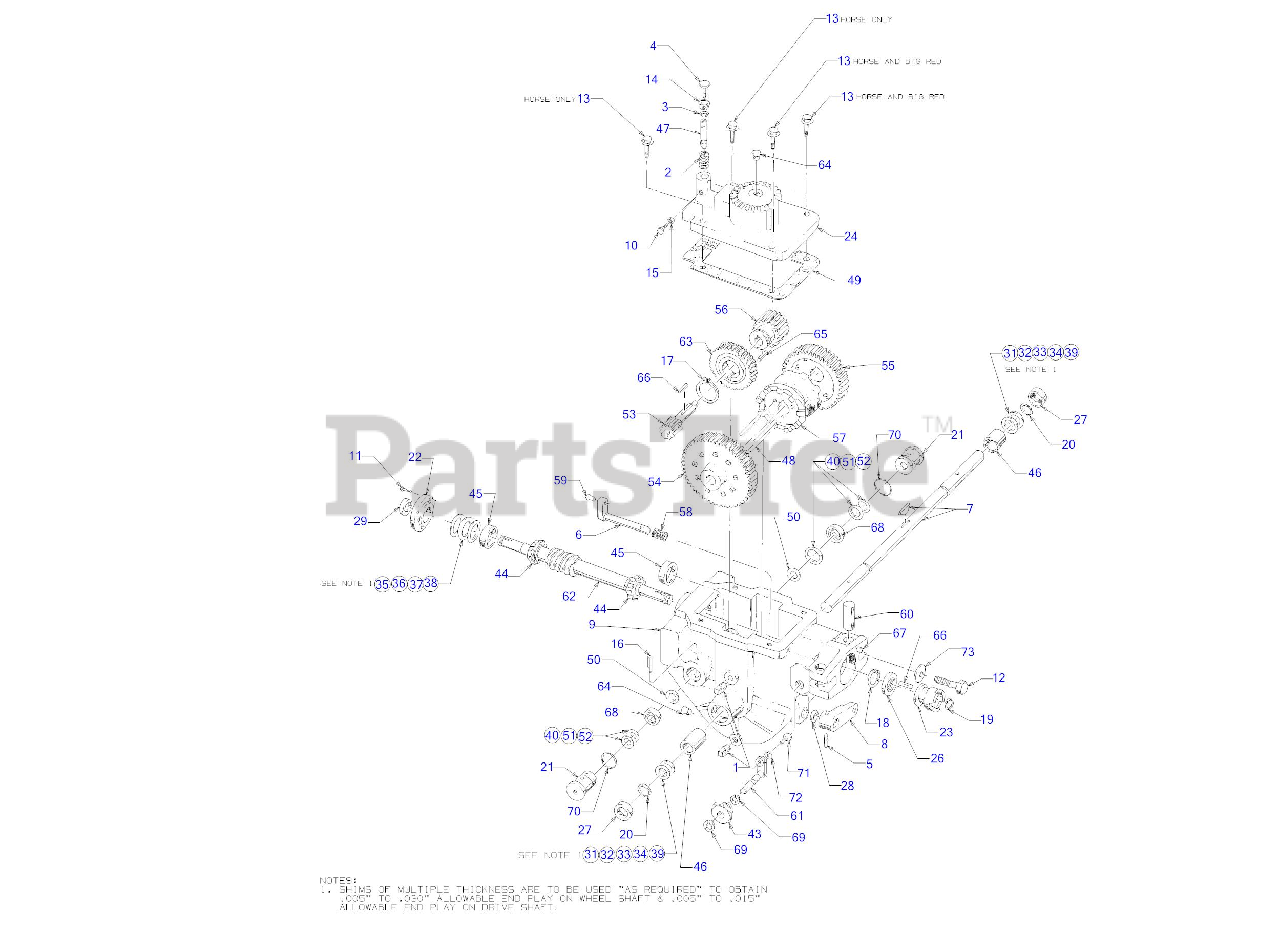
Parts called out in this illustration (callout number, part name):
1	PLUG-PIPE SQ HD 1/
2	SPRING-REV PLUNGER
3	RING-KLIP
4	SCREW 3/8-16X1.5 UNC
5	SPRING PIN .188X1.
6	ECCENTRIC SHAFT
7	HORSE WHEEL SHAFT ASSEMBLY W/KEY
7	KEY:HI-PRO
8	ECCENTRIC ARM
9	NOT SERVICEABLE
10	SCREW 5/16-18 x 1.0 GR5
11	SCREW 1/4-20 x .75 GR5
12	SCREW 1/2-13 x 2 GR5
13	SCREW 3/8-16 x 1.50
15	HEX NUT
16	SPRING PIN1/4 x 2.00
17	SNAP RING
18	RETAINING RING
19	RETAINING RING
20	RETAINING RING
21	BEARING RETAINING PLUG
22	FRONT BEARING COVER
23	PTO TRANS CLUTCH
24	TRANS COVER
26	OIL SEAL .750 SHF x 1.783
27	OIL SEAL 1.0 SHF x 1.499
28	OIL SEAL .625 SHF x 1.000
31	FLAT WASHER: 1.015 x 1.375 x .005
32	FLAT WASHER 1.015 x 1.375 x .010
33	FLAT WASHER 1.015 x 1.375 x .015
34	FLAT WASHER 1.015 x 1.375 x .030
35	FLAT WASHER 1.500X1.750X.062
36	FLAT WASHER 1.500X1.750X.005
37	FLAT WASHER 1.500X1.750X.030
38	FLAT WASHER 1.500X1.750X0.010
39	FLAT WASHER 1.015X1.375X.062
40	FLAT WASHER 1.015X1.234X.062
43	ECCENTRIC BUSHING
44	BEARING CONE
45	BEARING CUP
46	BUSHING 1.005 x 1.25 x 1.5
47	NEUTRAL PLUNGE AS
48	PIN-CLUTCH
49	TRANSMISSION COVER GASKET
50	FLAT WASHER .510X.
51	SHIM
53	SPLINE GEAR 10 TEETH
54	SPUR GEAR 56 TEETH
55	SPUR GEAR
56	SPUR GEAR 20 TEETH
57	CLUTCH DOG
61	SGAFT-WELD ECCENTR
62	SHAFT-WHEEL DRIVE
63	WORM GEAR
64	PLUG-CAP (RED)
66	KEY .188 x 1.0
67	PIN-DRIVE
68	BALL BEARING
69	RETAINING RING
71	SCREW-SOCKET HE
72	LOCK WASHER
73	WASHER-DISC SPRING
